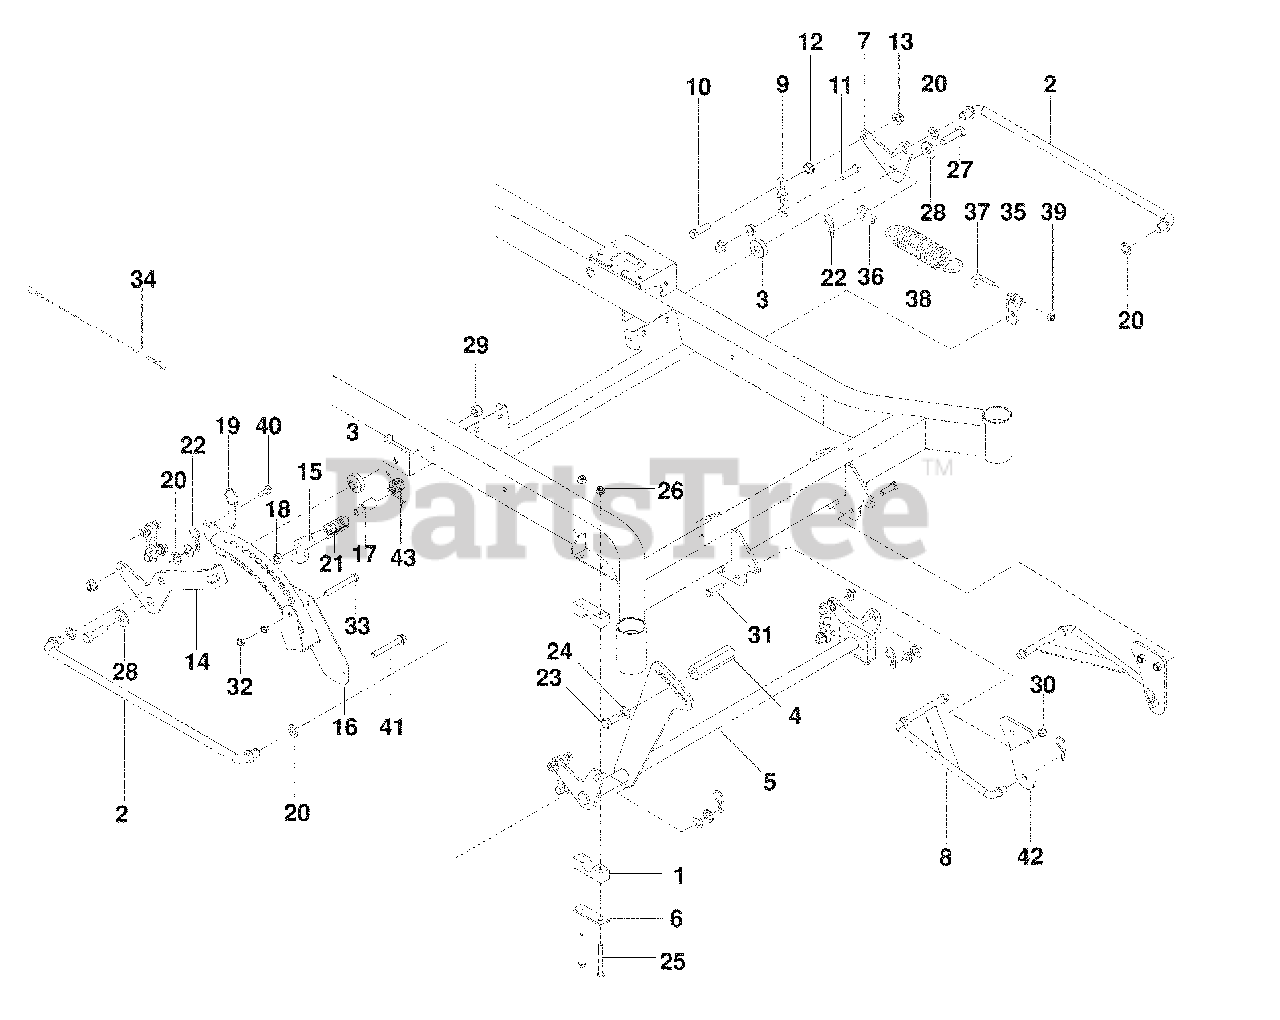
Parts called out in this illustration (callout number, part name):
1	PILLOW BLOCK
2	DECK LIFT LINK
3	SPACER, IDLER
4	PEDAL, FOOT, HEX
5	SHAFT, FRONT-LIFT
6	REINFORCEMENT BAR
7	BELLCRANK, RR, LIFT
8	STRUT LINKAGE
9	LIFT CHAIN-3 LINK
10	BOLT, HEX 7/16-14 x 1½
11	BOLT, HEX 7/16-14 x 1¾
12	NUT 7/16-14 HEX WHIZ LK
13	NUT 7/16-14 HEX WHIZ LK
14	BELLCRANK, RR, RT
15	LATCH, TRANSPORT
16	HEIGHT, ADJUST, DECK
17	PIVOT, LATCH, TRANSPORT
19	PIN ½ x 1½ DETENT RING
20	BUSHING .625
22	PIN, COTTER 1¾
23	BOLT, HEX ½-13 x 1¾
24	WASHER 7/16" SPRING
25	BOLT, HEX 5/16-18 x 2¾
26	NUT 5/16-18 FLANGE NYLOC
27	BOLT, HEX ½-13 x 1¾ GR 8
28	WASHER ½ FLAT
29	NUT ½ HEX NYLOC
30	NUT 3/8-16 HEX NYLOC
31	BOLT, HEX 5/16-18 x 1 THD FM
32	NUT 3/8-16 HEX JAM NYLOC
33	BOLT, HEX 3/8-16 x 3
35	MOUNT, SPRING
36	TAB, SPRING
39	NUT 5/16-18 HEX NYLOC
40	BOLT 5/16-18 x ¾ THD FRM
41	SCREW, HX FLG 3/8-16 x 2¾
42	MOUNT, STRUT
43	SPRING, TORSION
